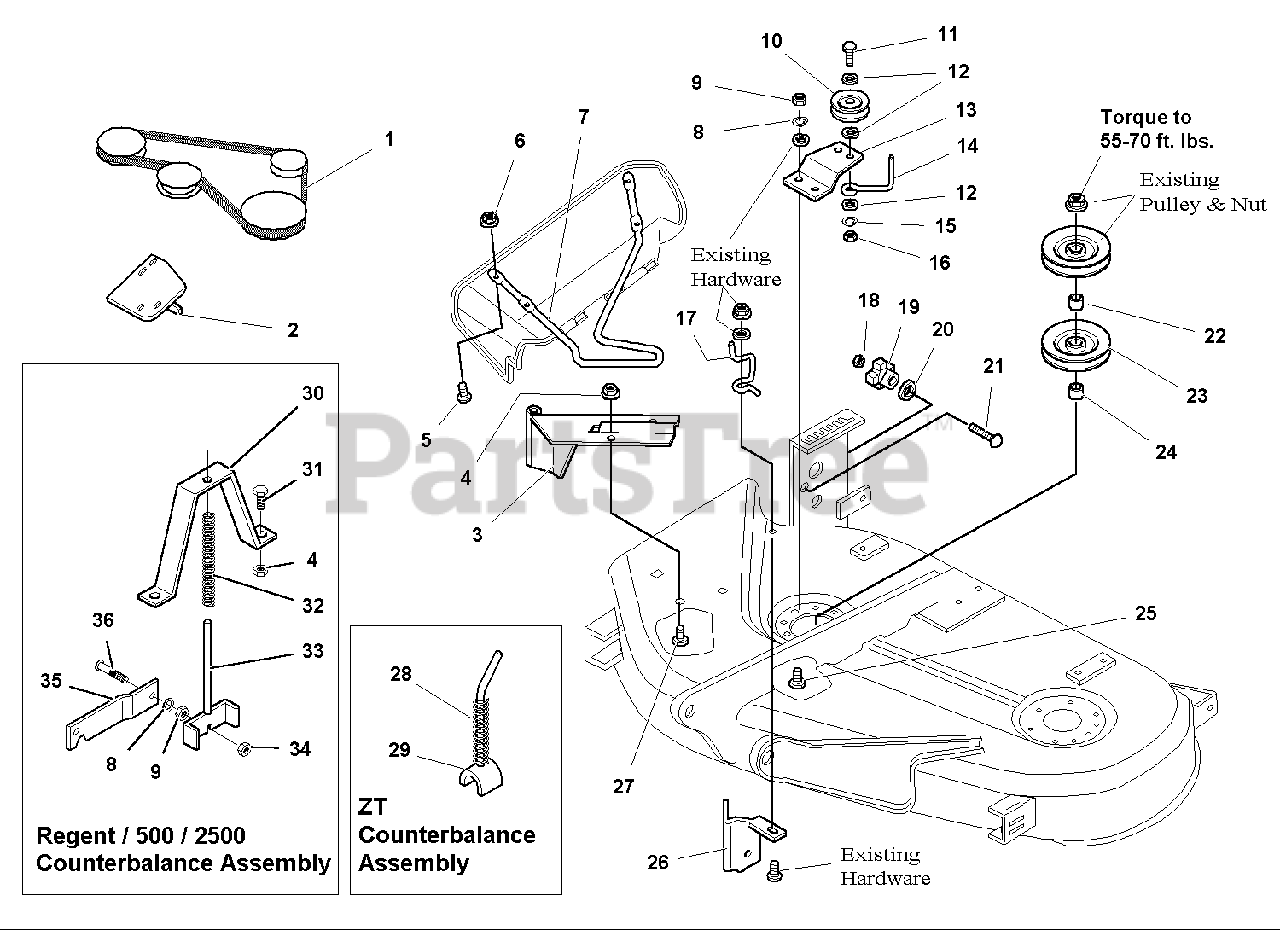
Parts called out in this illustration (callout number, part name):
2	MOUNTING BRACKET
3	PIVOT BRACKET
4	LOCKNUT, Flange, 5/16-18
5	SCREW, Truss Hd., 10-24 x 3/4
6	NUT, Nylock, 20-24
7	ROD, Deflector
8	LOCKWASHER
9	NUT, 5/16-18
10	PULLEY, Idler, 2-3/4" OD
11	CAPSCREW, 3/6-16 x 1-3/4
12	WASHER, 3/8
15	LOCKWASHER, 3/8
16	NUT, 3/8-16
17	SPRING LATCH
18	LOCKNUT, Centerlock, 5/16-18
20	WASHER, 5/16
21	CARRIAGE BOLT, 5/16-18 x 1-1/2
22	SPACER, Short, Splined
23	PULLEY, 5" OD
24	SPACER, Long
25	SCREW, Taptite, 5/16-18 x 1-1/2
27	CARRIAGE BOLT, 5/16-18 x 3/4
28	SPRING, Compression (Short)
29	LEVER ASSEMBLY, ZT
30	BRACKET, Counterbalance
31	SCREW, Whiz-Lock, 5/16-18 x 3/4
32	SPRING, Compression (Long)
33	ROD ASSEMBLY, Counterbalance
34	NUT, Flange, 2-Way Lock, 5/16-18
36	CARRIAGE BOLT, 5/16-18 x 1-1/4
